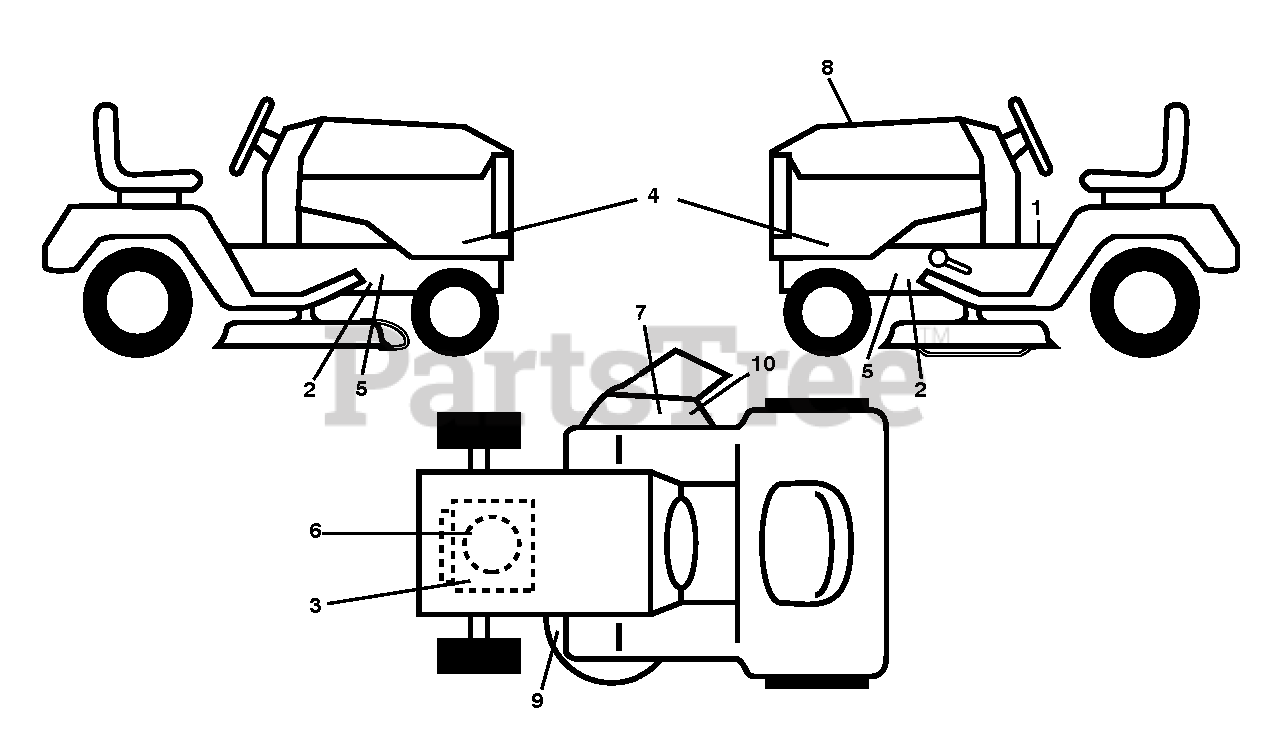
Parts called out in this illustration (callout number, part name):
1	DECAL TRACTOR SADDLE DECAL DEC
2	DECAL.WARNING.SERVCE/FIRE
3	DECAL.ENGINE.WARNING
5	DECAL.WARNING.HOT.MUFFLER.2021
6	DECAL.ENG.BS.656CC.HS.382274
7	DECAL.DECK.DEFLECTOR.WARNING
9	DECAL.DECK.BELT.ROUTE.42"2021
10	DECAL.DFLCTR.WARNNG.CTFNGR.SYM
